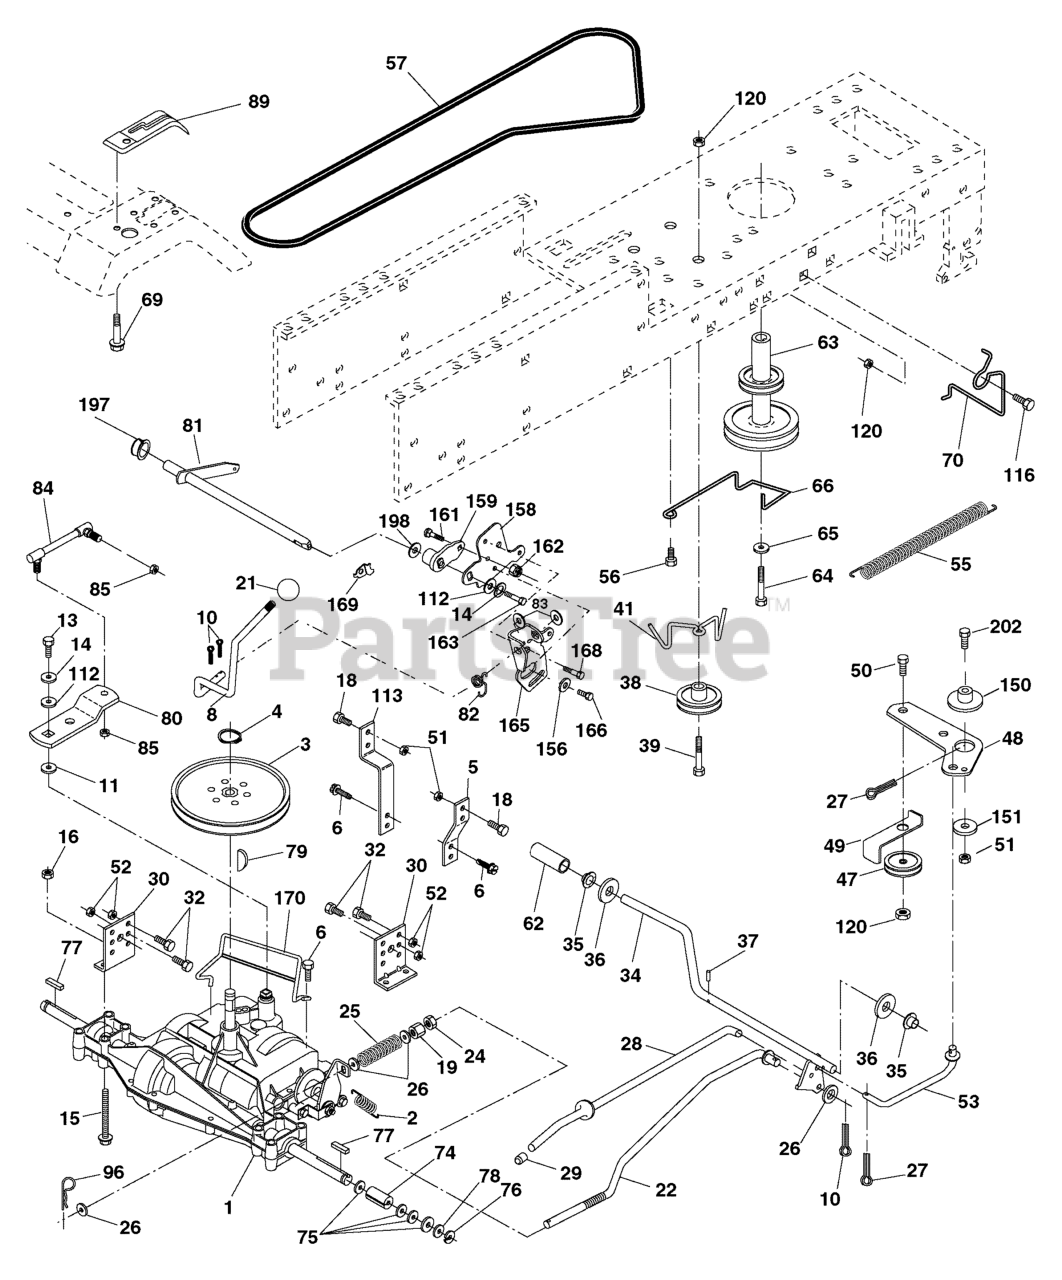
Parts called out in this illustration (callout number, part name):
2	SPRING RETURN, Brake T/a Zinc
3	PULLEY, Transaxle 18" tires
4	RING, Retainer # 5100-62
5	STRAP, Torque 30 Degrees
6	SCREW 5/16-18 x 3/4
8	ROD, Shift Fender Adjust Lt
10	PIN, Cotter 1/8 x 1 Cad
11	WASHER, Plate Shf 388 Sq Hole
13	BOLT, 1/4-28 unf Gr. 8 W/Patch
14	WASHER, Lock Hvy Helical
15	BOLT, Hex FLGHD 5/16-18 Gr. 5
16	NUT, Lock Hex w/ins 5/16-18
18	BOLT, Fin Hex 3/8-16 unc x 1 Gr. 5
19	NUT, Lock 3/8-16 unc
22	ROD, Brake Blk Zinc 26 840
24	NUT, Hex Jam 3/8-16 unc
25	SPRING, Rod Brake 2 00 Zinc
26	WASHER, 13/32 x 13/16 x 16 Ga.
27	PIN, Cotter 1/8 x 3/4 Cad
28	ROD, Brake Parking LT/YT
29	CAP, Brake Parking
30	BRACKET, Mtg Transaxle
32	BOLT, Hex Hd 5/16-18 unc x 3/4
34	SHAFT ASM., Pedal Foot
35	BEARING, Nylon Blk 629 Id
36	WASHER 21/32 x 1 x 16 Ga.
37	PIN, Roll 3/16 x 1"
38	PULLEY, Composite Flat
39	BOLT, RDHD 3/8-16 unc x 2-3/4 Gr. 5
41	KEEPER,r Belt Flat Idler
47	PULLEY, Idler V Groove Plastic
48	BELLCRANK ASSEMBLY
49	RETAINER, Belt Style Spring
50	BOLT, Carriage, Sh. 3/8-16 x 1-1/2 Gr. 5
51	NUT, Crownlock 3/8-16 unc
52	NUT Crownlock 5/16-18 unc
53	LINK, Clutch
55	SRRING RETURN, Clutch 6 75
56	SCREW, 3/8-16 x 1-1/4
57	V-BELT, Ground Drive 95 30
62	COVER, Pedal Blk Round
63	PULLEY, Engine
64	BOLT, Hex
65	WASHER, Lock Hvy Hlcl Spr 7/16
66	KEEPER, Belt Engine Foolproof
69	SCREW, Hex wsh HiLo 1/4 x 1/2 unc
70	GUIDE, Belt Mower Drive RH
74	SPACER, Axle
75	WASHER, 25/32 x 1 1/4 x 16 Ga.
76	E-RING, #5133-75
77	KEY, Square 2 0 x 1845/ 1865
78	WASHER, 25/32 x 1-5/8 x 16 Ga.
79	KEY, Woodruff #9 3/16 x 3/4
80	ARM, Shift
81	SHAFT ASSEMBLY, Cross Tapered PMST/20
82	SPRING, Torsion T/a
83	WASHER, 17/32 x 3/4 x 16 Ga.
84	LINK, Transaxle Dana/18" Zinc
85	NUT, Lock Center 1/4 - 28 FNTHD
89	CONSOLE, Shift STLT
96	RETAINER, Spring 1"
112	WASHER, 9/32 x 3/4 x 10 Ga.
113	STRAP, Torque LT
116	BOLT, Carriage, 3/8-16 x 1
120	NUT, Lock Flg. 3/8-16 unc
150	SPACER, Retainer
151	WASHER, 13/32 x 2 x 10
156	WASHER, Srrted 5/16ID x 1.125
158	BRACKET, Shift Mount
159	HUB, Tapered Flange Shift Lt
161	BOLT, Carriage, 1/4-20 x 3/4
162	NUT, Crownlock 1/4-20 unc
163	BOLT, Hex Fin 1/4-20 unc x 1 Gr. 5
165	BRACKET, Pivot Lever
166	SCREW, 5/16-18 x 5/8
168	BOLT, Shoulder 5/16-18 x .561
169	PLATE, Fastening
170	KEEPER, Belt Transaxle Gear
197	NYLINER, Snap-In
198	WASHER, Nyliner
202	BOLT, RdHd 3/8-16 unc x 1-3/4 Gr. 5
